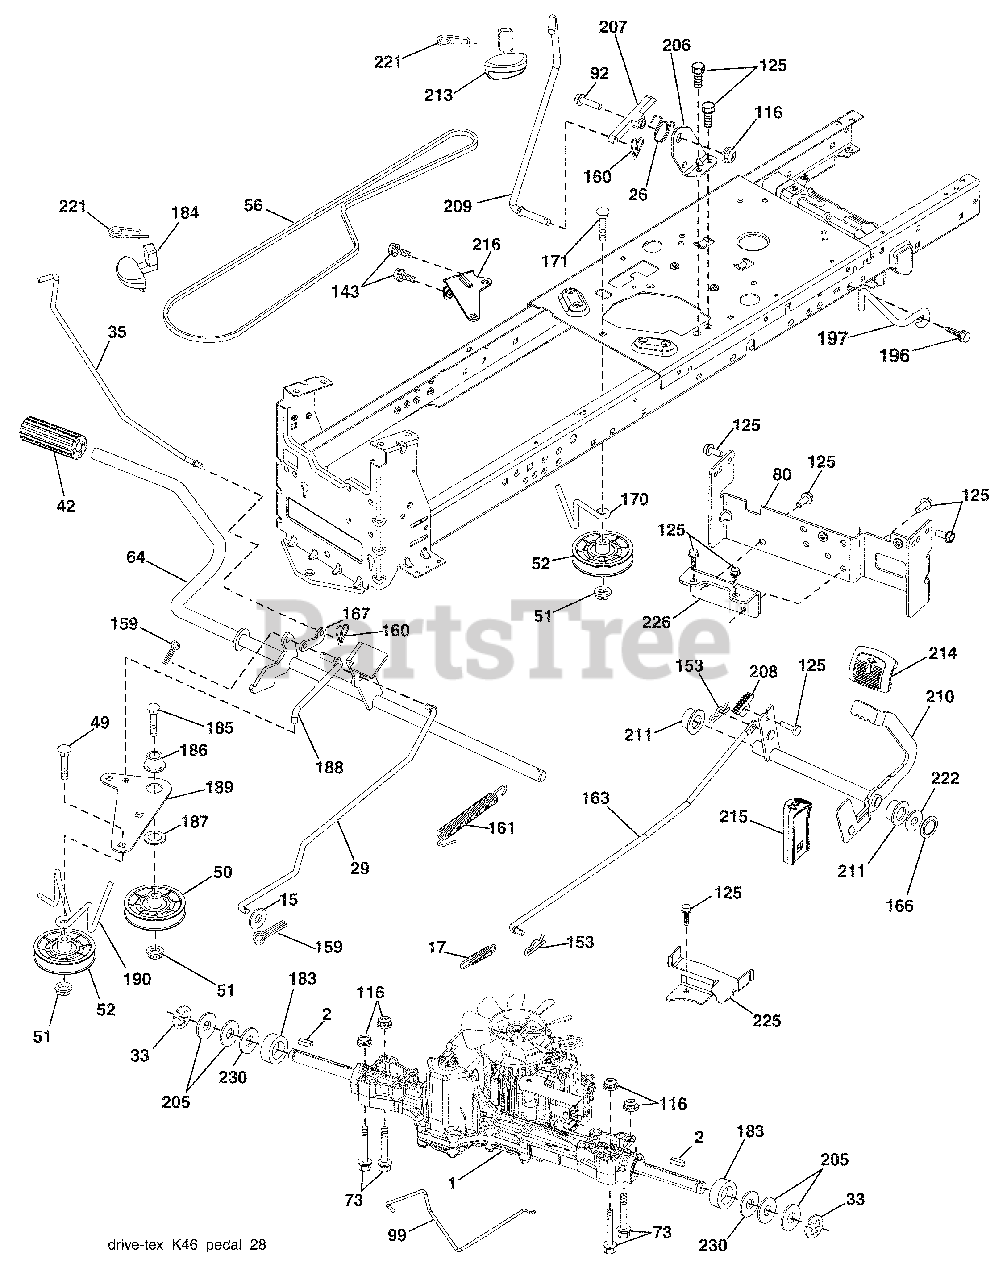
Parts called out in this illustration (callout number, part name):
1	Transaxle, TUFFTORQ K46 BT (Internal parts not available)
15	Washer 13/32 x 13/16 x 16 Ga.
17	Spring, Brake
26	Spring Return Cruise
29	Rod, Brake
35	Rod, Brake, Park
42	Cover, Foot Pedal
50	Pulley Idler Flat
51	Lock Nut 3/8-16
52	Idler V-Groove 910 Offset"
56	V-Belt, Drive
64	Shaft Asm. Pedal Brake Control
73	Bolt Hex Flghd 5/16-18 Gr. 5
80	Bracket Strap Torque
92	Bolt Fin Hex 5/16-18 unc x 1.25
99	Rod Asm. Bypass
116	Nut Lock Hex Flange 5/16-18
125	Screw 5/16-18 x 3/4
143	Screw 5/16-18 x 1/2
153	Retainer Spring
159	Pin Cotter 1/8 x 3/4
160	Retainer Clip
161	Spring, Return, Clutch
163	Rod Pedal Control
166	Nut Push
167	Latch Brake Parking
170	Keeper Belt Centerspan
171	Bolt RDHD SQNK 3/8-16 unc x 2
183	Spacer Split
184	Handle Parking Brake
185	Bolt Rdhd Sqnk 3/8-16 x 2-1/2
186	Spacer Retainer
187	Washer
188	Link Clutch Ground Drive
189	Bellcrank Ground Drive
190	Keeper Bellcrank Ground Drive
196	Screw 3/8-16 x 1
197	Bracket Clutch Anti-Rotation
206	Bracket Mount Latch Cruise
207	Latch Control Cruise
208	Gear Sector Control Cruise
209	Rod Control Cruise
210	Rocker Asm. Pedal Control
211	Bearing Nylon
213	Knob Control Cruise
214	Pedal Forward
215	Pedal Reverse
216	Bracket Pulley Idler
221	Retainer Spring Clip Handle
222	Washer 21/32 x 1-1/4 x 10 Ga.
225	Keeper Belt Trans.
226	Bracket Mount Torque
230	Washer Hardened
